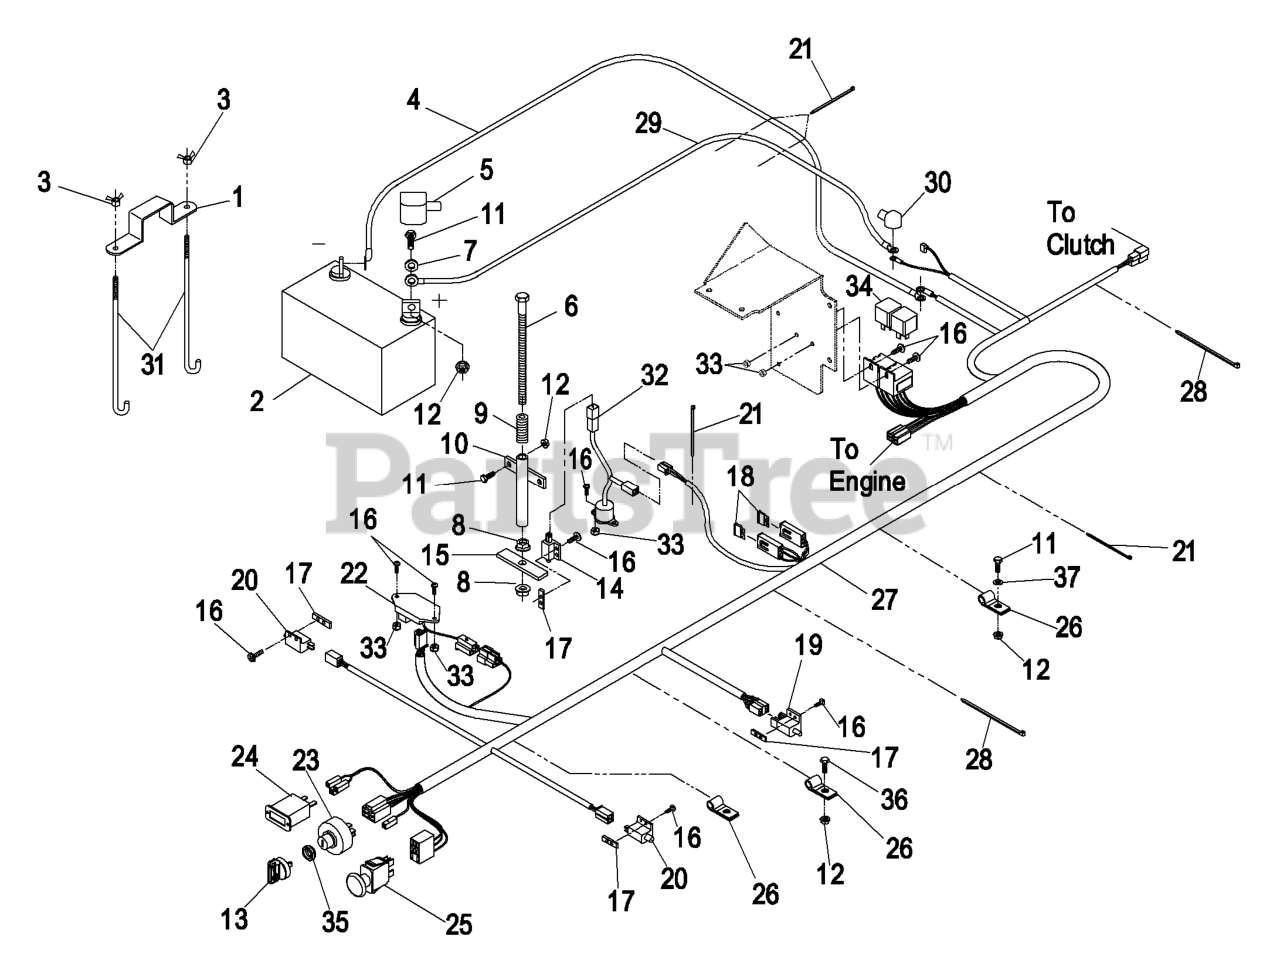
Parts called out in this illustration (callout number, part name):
1	STRAP-HOLDDOWN
3	WINGNUT
4	WIRE-GROUND
6	SCREW-HH
7	WASHER-FLAT
9	SPRING-SWITCH, SEAT
10	MOUNT-SPRING, SEAT
11	SCREW-HH
13	KEY-IGNITION
14	SWITCH-CLOSED, NORMALLY
15	PLATE-SWITCH, SEAT
16	SCREW-PPH
17	PLATE-TAPPED
18	FUSE-BLADE TYPE, 20 AMP
20	SWITCH-OPEN, NORMALLY
21	TIE-CABLE
22	MODULE-DELAY, SEAT
24	METER-HOUR
26	CLIP-LOOM
27	HARNESS,WIRE KC
28	TIE-PLASTIC
30	INSULATOR-SOLENOID
31	BOLT-HOLDDOWN
33	NUT-LOCK, NI
35	NUT-SWITCH, IGNITION
36	SCREW-HH
37	WASHER-FLAT
